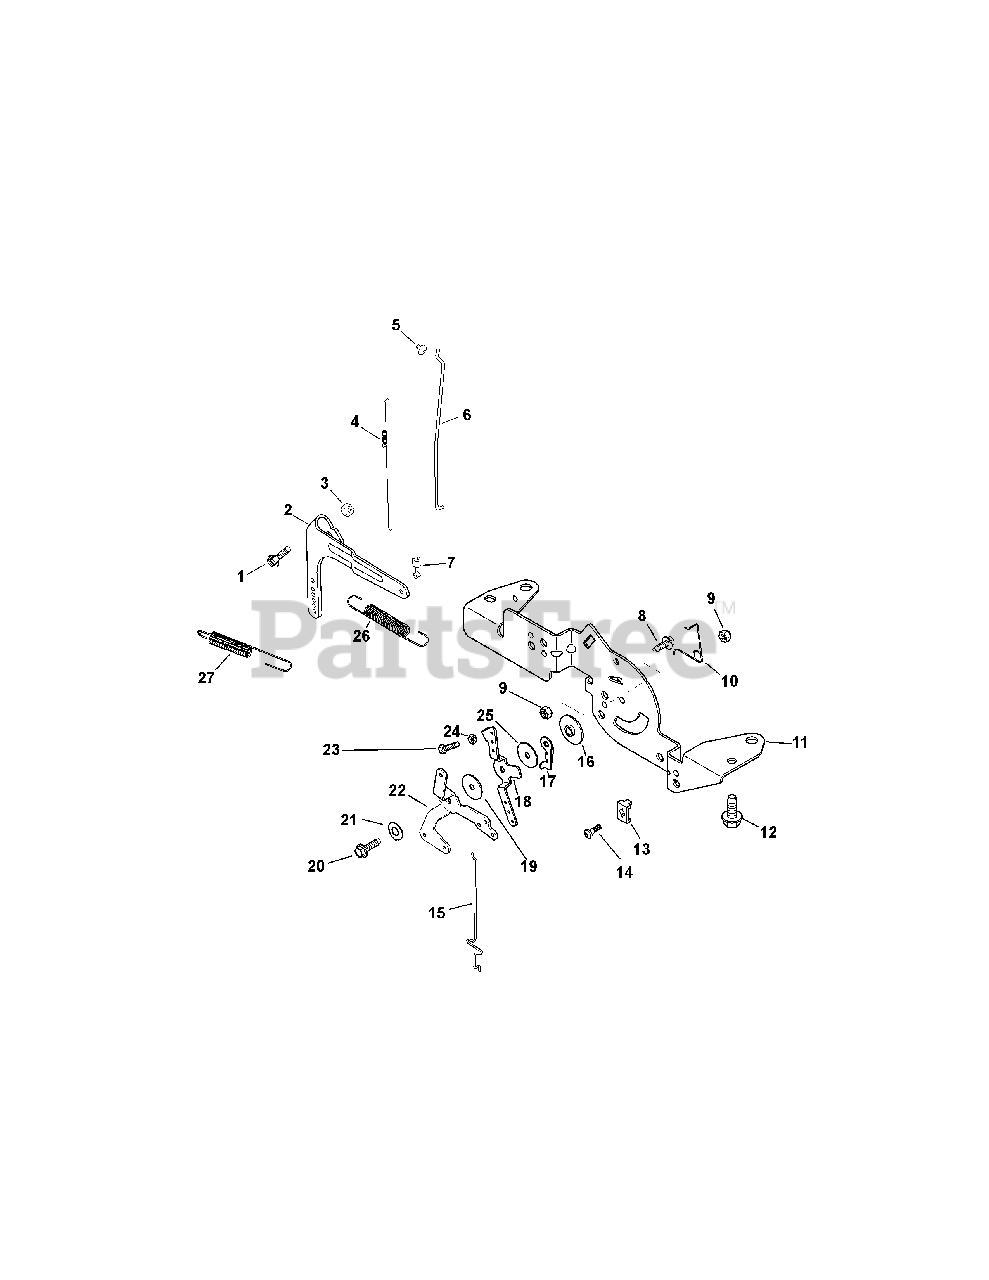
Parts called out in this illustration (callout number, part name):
1	Rd. Hd. Sq. Neck Bolt, M6 x 1.0 x 25
2	Governor Lever
3	Flg. Nut, M6 x 1.0
4	Linkage Spring
5	Linkage Retaining Bushing
6	Throttle Linkage
7	Throttle Linkage Bushing
8	Screw, M5 x .8 x 16
9	Lock Nut, M5 x .8
10	Choke Return Spring
11	Control Bracket
12	Flg. Thd. Frm. Screw, M6 x 1.0 x 16
13	Cable Clamp
14	Lbd. Thd. Frm. Screw, M5 x 0.8 x 16
15	Choke Linkage
16	Control Assembly Spacer
17	Throttle Actuator Lever
18	Throttle Control Lever
19	Flat Washer, 5.5MM
20	Screw, M5 x .8 x 20
21	Spring Washer, 1/4"
23	Screw, M4 x .7 x 25
25	Flat Washer, 5MM
26	Governor Spring
27	Governor Spring
